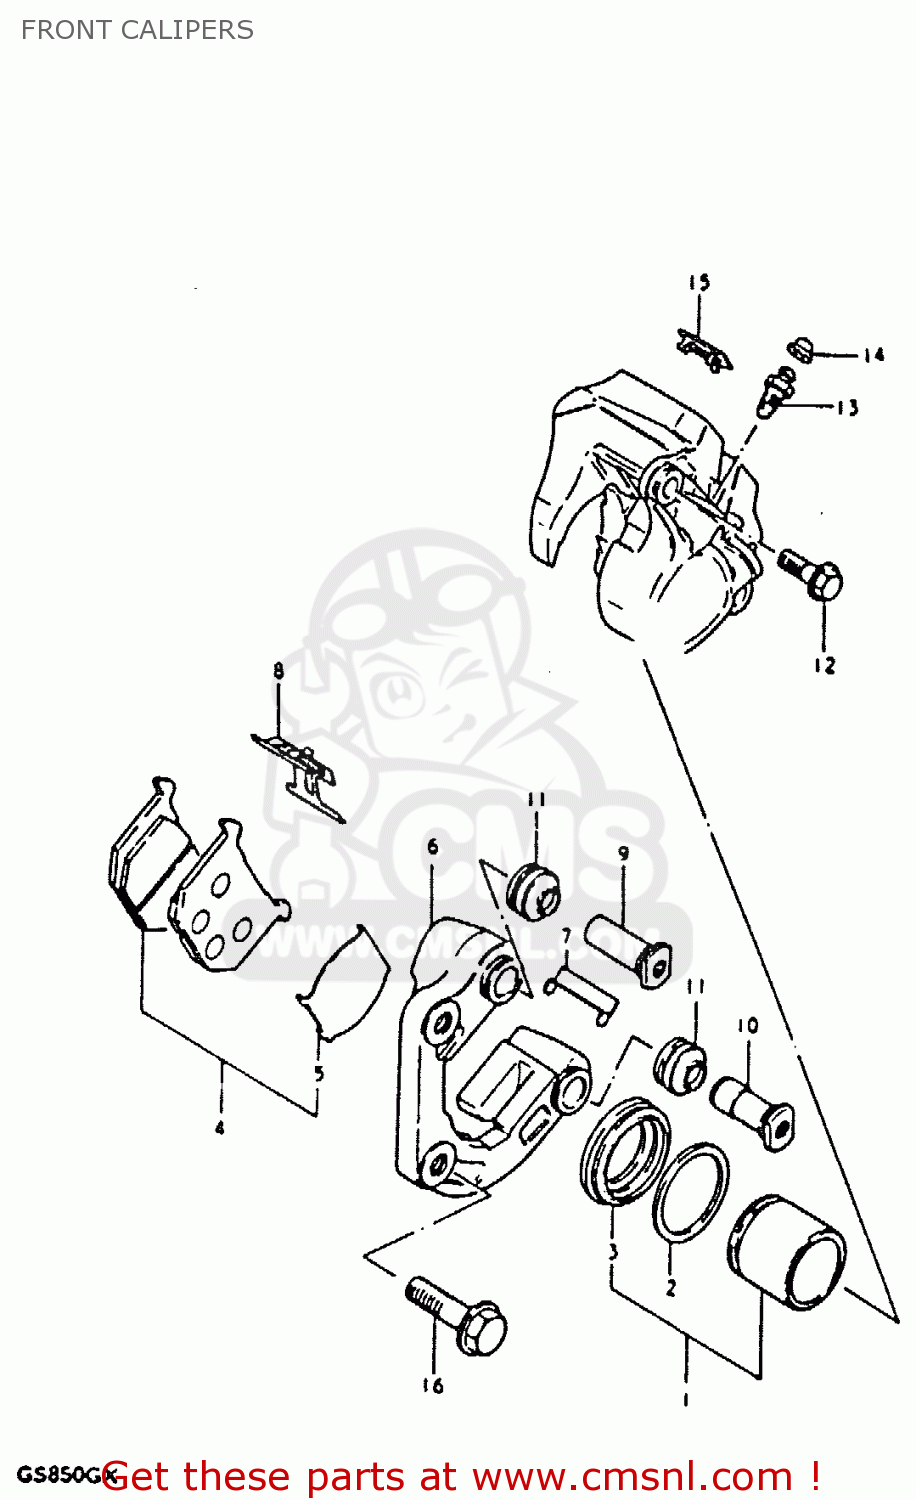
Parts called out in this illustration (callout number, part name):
1	PISTON SET
2	SEAL,PISTON
3	BOOT,PISTON
4	PAD SET (MCA)
5	SHIM,PAD
6	CARRIER,CALIPER,LEFT
7	GUIDE,PAD
8	SPRING,PAD
9	AXLE NO.1
10	AXLE NO.2
11	BOOT,AXLE
12	BOLT,CALIPER HOUSING
13	BLEEDER
14	CAP,BREATHER
15	COVER,INDICATOR
16	BOLT(10X37)
